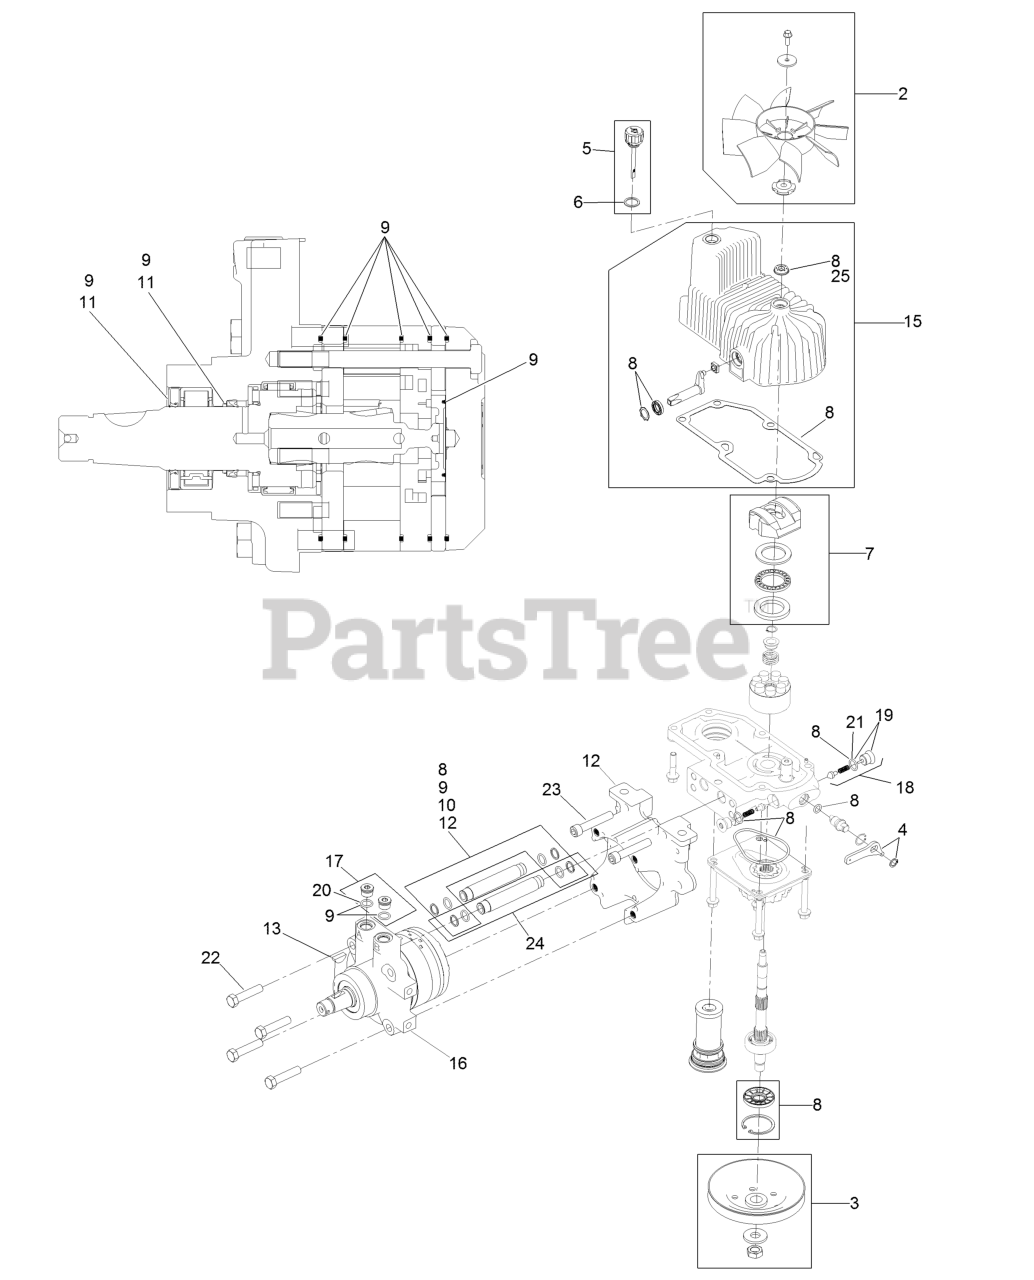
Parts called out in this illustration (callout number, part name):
2	Fan Kit
3	Pulley Kit
4	Handle-Bypass Valve, Hydro
5	Dipstick-Hydro W/Gasket
6	Gasket-Dipstick, Hydro
7	Swash Block Kit
8	Pump Seal Kit
9	Motor Seal Kit
10	Tube Seal Kit
11	Output Shaft Seal Kit
12	Nose Cup-Uht
13	Key-Woodruff
15	Housing-LH
16	Motor-Hydraulic LH 240Cc
17	Magnetic Plugs Service Kit
18	Check Valve ASM
19	Plug-Check (W/O-Ring)
21	O-Ring-Check Valve
22	Screw HH
23	Screw-HSH
24	Hydraulic Tube Kit
25	Seal-Fan Drive
99	Flow Test Kit
99	Puller-Pulley
